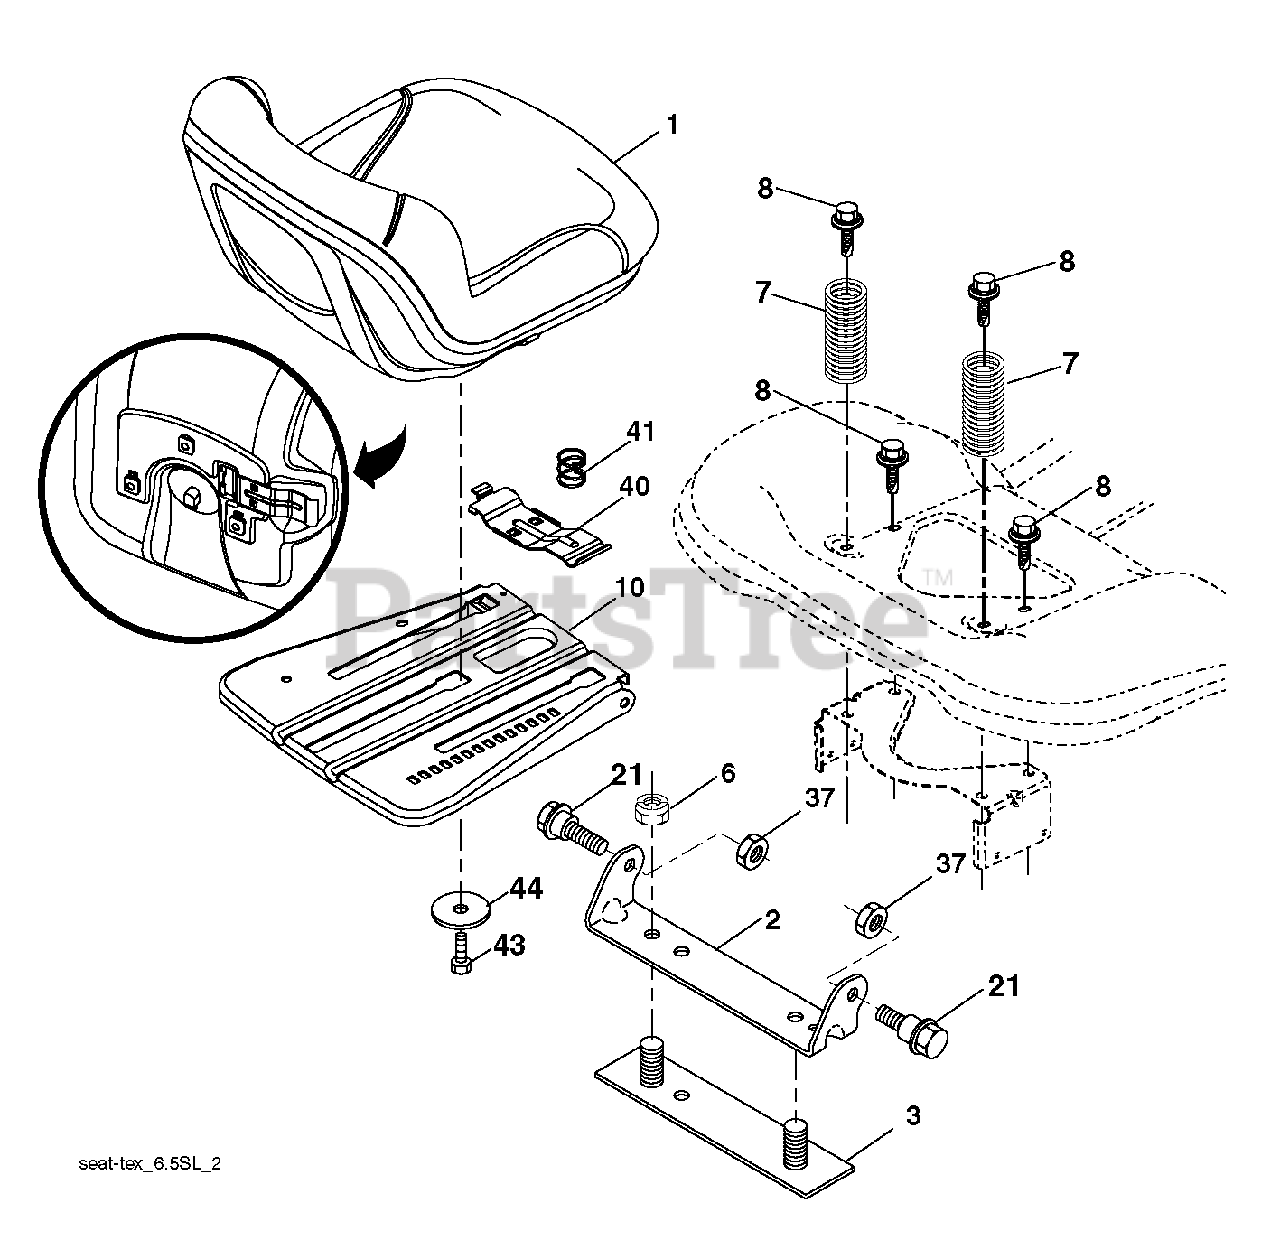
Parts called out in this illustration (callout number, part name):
1	SEAT.TH130.GREY.HUSQ.TEX
2	BRKT.PIVOT.FENDER
3	STRAP
6	NUT
7	SPRING COMPRESSION
8	BOLT, 5/16-18 X 1 3/4
10	PAN.ASM.SEAT.3PT
21	BOLT.SHOULDER.5/16-18
37	NUT.71038.31-18.HEX.NYLOCK
40	HANDLE.SLIDE.SEAT.TEX.BLACK
41	SPRING.LATCH.SEAT.TEX
44	WASHER 13/32 X 2-3/8 X 12GA
